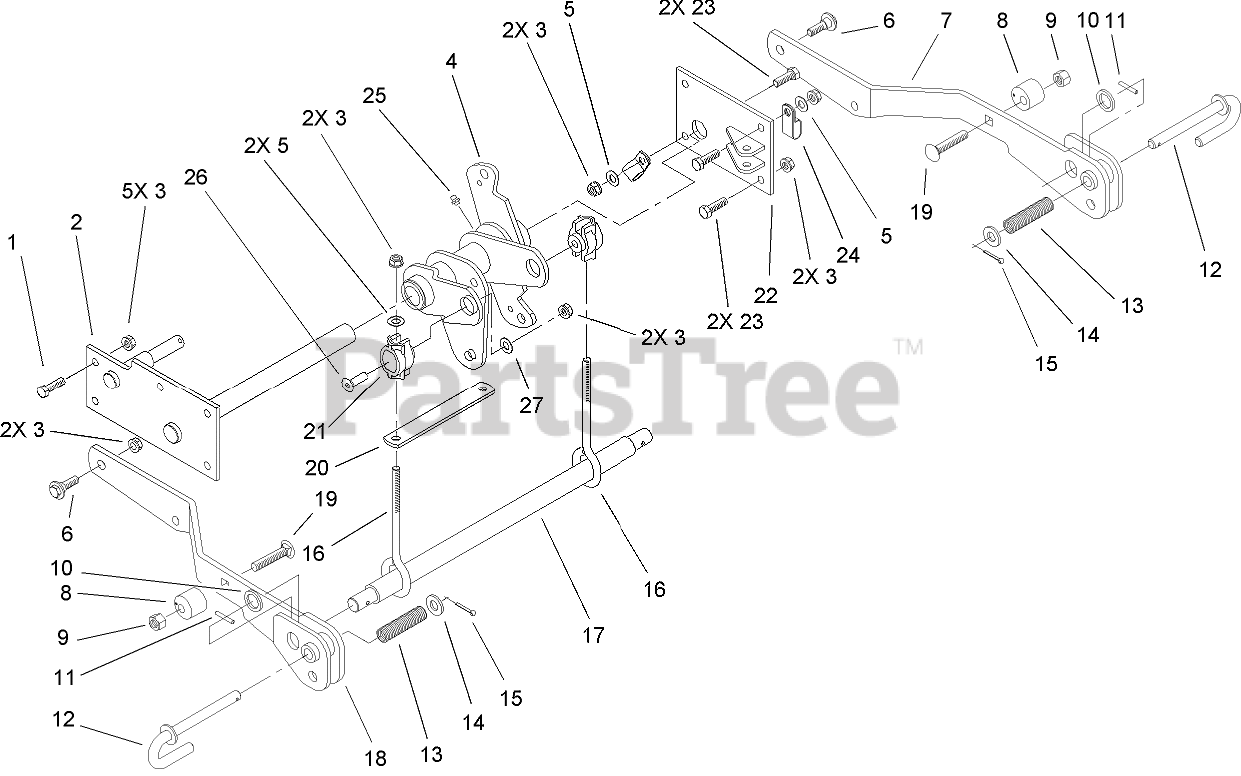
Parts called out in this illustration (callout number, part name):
1	SCREW-HH
2	SUPPORT-LIFT, DECK
3	NUT-LOCK, NI
4	BELLCRANK AND BUSHING ASM
5	WASHER-FLAT
6	BOLT-SHOULDER
7	ARM-LIFT, LH
8	STOP-LIFT, ADJ.
9	NUT-LOCK, NI
10	WASHER-FLAT
11	PIN-ROLL
12	PIN - J
13	SPRING-COMPRESSION
14	WASHER-FLAT
15	PIN-COTTER
16	ROD-LIFT
17	BAR-LIFT
18	Arm-Lift, RH
19	SCREW-CARR
20	SPACER-STRAP
21	SLEEVE-LIFT
22	SUPPORT-CYLINDER
23	SCREW-HH
24	CLAMP-TUBE
25	FITTING-GREASE
26	SCREW-HSFH
27	WASHER-FLAT
